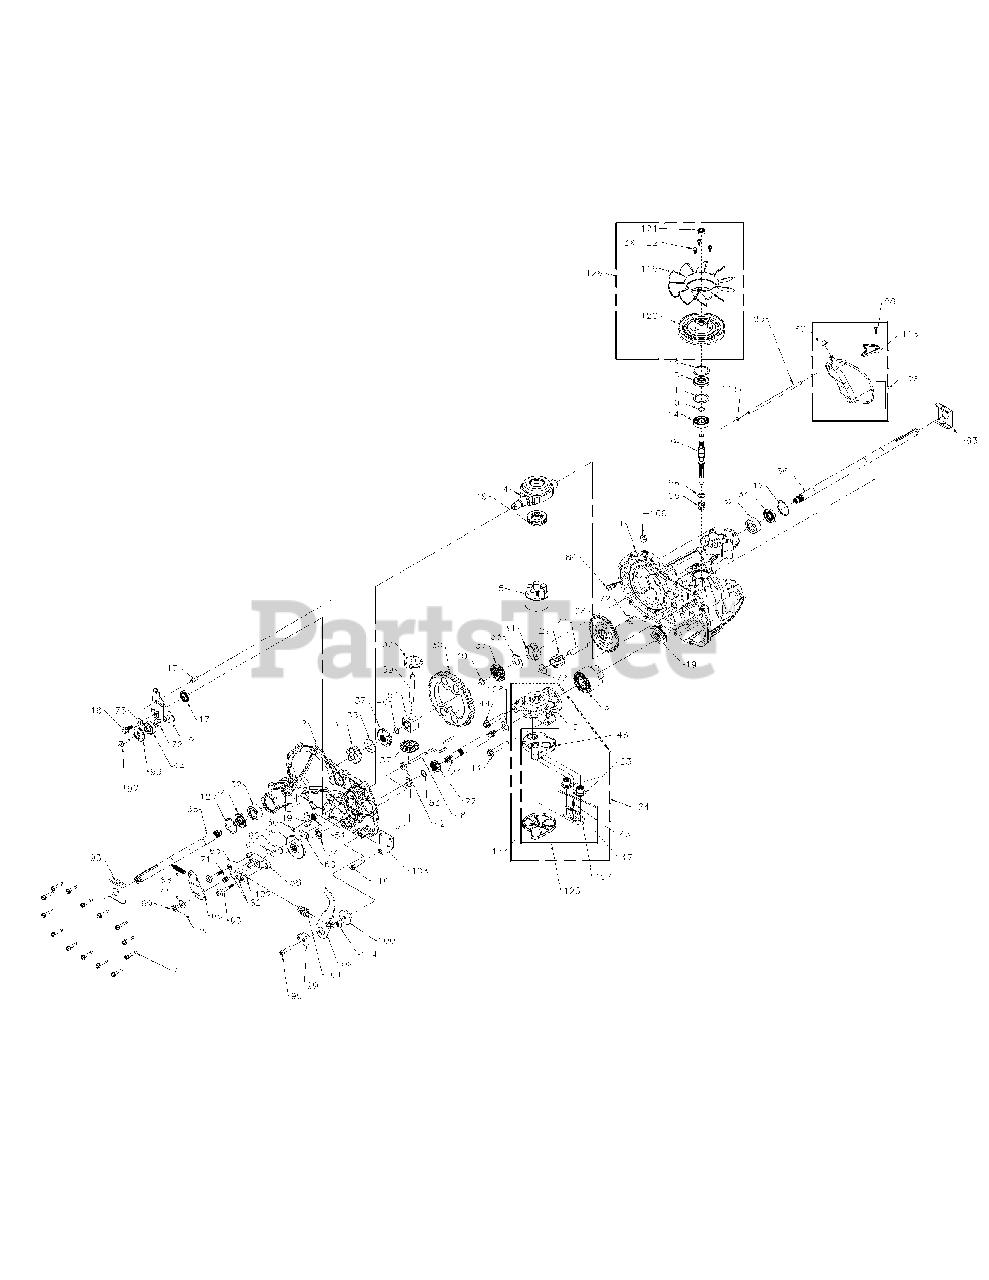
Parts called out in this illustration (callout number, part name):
1	Main Housing, Assembly
1	Main Housing
1	Bushing .865 X .985 X .790
1	Pin, Standard Headless
2	Side Housing, Assembly
2	Side Housing
2	Bushing .865 X .985 X .790
2	Bushing .624 X .719 X .562
3	Center Section, Assembly
3	Center Section
3	Bushing .707 X .788 X .591
4	Trunnion, Swashplate
5	Block, Assembly
5	Block, Cylinder
5	Piston
5	Spring, Compression
5	Washer, Thrust
7	Screw, Hex Flange 1/4-20 X 1.25
9	Shaft, Input
10	Ring, Retaining
12	Ring, Retaining
13	Seal, Lip 17 X 40 X 7
14	Bearing Ball 17mm ID X 40mm OD X 12mm
16	Bolt, Hex Flange Head 5/16-24 X .94 (Patch)
17	Seal, Lip 18 X 32 X 7
18	Arm, Control
19	Bearing, Thrust 30 X 52 X 13
23	Check Plug Assembly, .027 Washer
24	Shaft, Motor
27	Gear, 13T Pinnion
28	Gear, 10T/48T
29	Gear 10T Jackshaft
30	Gear, 60T Bull
31	Bushing, Sleeve (Inboard)
32	Bushing, Sleeve .75 X 1.575 X .625
33	Washer, 3/4 ID X 1-1/2 OD X .13 THK
34	Seal, Lip .75 X 1.577 X .250
35	Shaft, Axel .75 X 12.14 (Keyed, R.H.)
36	Shaft, Axel .75 X 17.74 (Keyed, L.H.)
37	Kit, Miter Gear
37	Gear, Miter 12T (Splined)
37	Gear, Miter 12T (.50 ID)
37	Bulletin, Miter Gear
39	Shaft, Diff
40	Ring, Spiral Retaining
41	Pin, Jackshaft
42	Magnet, Ring
43	Spring, Bypass
44	Bolt, Hex Flange 3/8-24 X 2.5
45	Bottom, Filter
46	Base, Filter with Poppet
47	Actuator, Bypass
48	Rod, Actuator Bypass
49	Arm, Bypass
50	Ring, Retaining .250 External
51	Seal, Lip .250 X .750 X .250 TC
52	Washer, Flat 5/8 ID X 1.0 OD X .05
53	Ring, Retaining
54	Bushing, Center Block
55	Spring, Block
56	Washer, Thrust
58	Kit, Brake Yoke
58	Yoke, Brake
58	Bolt, SQ.HD. 5/16-24- Ribbed
59	Rotor, Brake
60	Puck, Brake
61	Plate, Puck
62	Pin, Brake Actuating
63	Screw, Special Flange 1/4-20 X 2 W/ Patch
66	Spring, Brake Arm Bias
68	Arm, Brake
69	Nut, Castle 5/16-24
70	Pin, Cotter 3/32 X 3/4
71	Spring, Compression Brake Anti-Drag
72	Washer, HT .5 ID X 1 OD X .032
73	Washer, Flat 11/32 ID X 7/8 OD
74	Seal, Lip .625 X 1.0 X .25
84	Fitting, 5/16 SAE 5/32 Tube
85	Hose, Expansion Tank
87	Cap, Expansion
88	Bolt, Self Tapping 10-32 X1/2
93	Spring Clip, Housing Thrust
94	Bearing, Ball .62 ID X 1.38 X .44
95	Screw, Socket Head Cap 5/16-24 X 1-1/2
96	Spacer, Locating
97	Screw, Countersunk 5/16-18 X 1
98	Arm, Return
99	Puck, Adjusting
100	Washer, .32 OD X 1.60 ID X .24
101	Spring, Extension Double Loop
102	Spacer, .260 ID X .560 OD X .870
103	Bracket, Torque
107	Deflector
108	Washer, Motor Shaft .71 ID X 1.15 OD X .030 THK
109	Plug, 9/16-18 (Metal)
110	Screw, Torx Head 5/16-18 T.F.
111	O-Ring .103 ID X .299 OD
113	Bracket, Support Expansion Tank
114	Spring Guide
117	Pin, Spring
119	Fan, 7 IN 10 Blade
120	Pulley, 4.79 Inch
121	Nut, Hex Lock 1/2-20 (Nylon Insert)
122	Screw, Tapping, Hex Washer Head, 12-24 X .50
124	Center Section, Filter, Bypass Assembly
124	Center Section
124	Base, Filter with Poppet
124	Check Plug Assembly, .027 Washer
124	Spring, Bypass
124	Actuator, Bypass
124	Deflector
124	Bottom, Filter
124	Bushing, .707 X .788 X .591
125	Filter Assembly
125	Bottom, Filter
125	Base, Filter with Poppet
125	Spring, Bypass
125	Actuator, Bypass
125	Deflector
126	Kit, Fan/Pulley
126	Fan, 7 IN 10 Blade
126	Pulley, 4.79 Inch
126	Nut, Hex Lock 1/2-20 (Nylon Insert)
126	Screw, Tapping, Hex Washer Head, 12-24 X .50
128	Kit, Expansion Tank
128	Tank, Expansion
128	Cap, Expansion
128	Bolt, Self Tapping 10-32 X1/2
128	Bracket, Support Expansion Tank
128	Seal, O-Ring Kit
128	Seal, Lip 17 X 40 X 7
128	Seal, Lip 18 X 32 X 7
128	Seal, Lip .75 X 1.577 X .250
128	Seal, Lip .250 X .750 X .250 TC
128	Seal, Lip .625 X 1.0 X .25
128	O-Ring .103 ID X .299 OD
